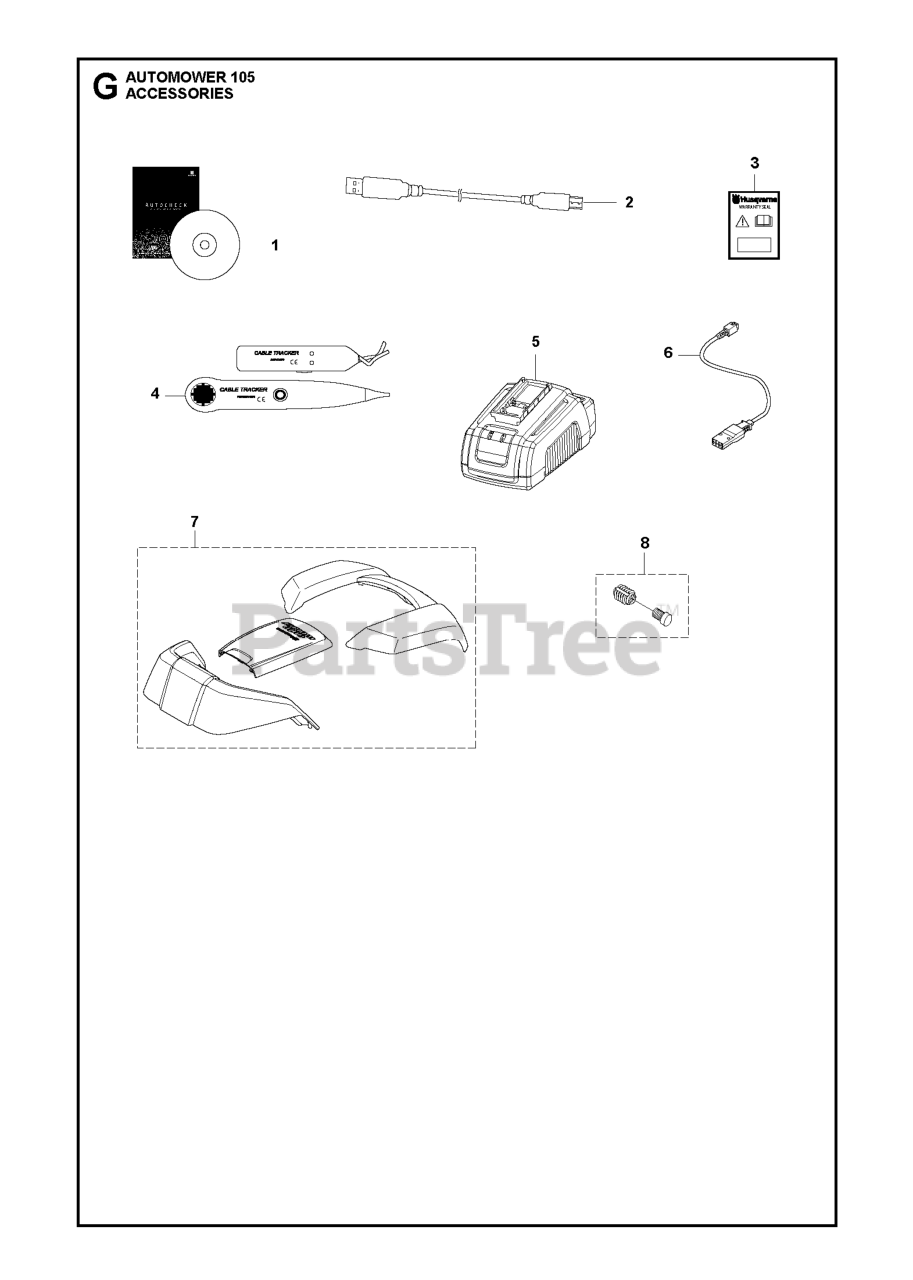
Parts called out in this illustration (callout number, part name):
1	DVD AUTOCHECK EXP SERVICE
2	CABLE WHITE ALT GREY
3	LABEL WARRANTY SEAL KIT 10 PK
4	TEST EQUIPMENT
5	CHARGER BATTERY TEST
6	CABLE ASSY QUICK CHARGER
8	THREAD INSERT KIT: THREAD INSE
